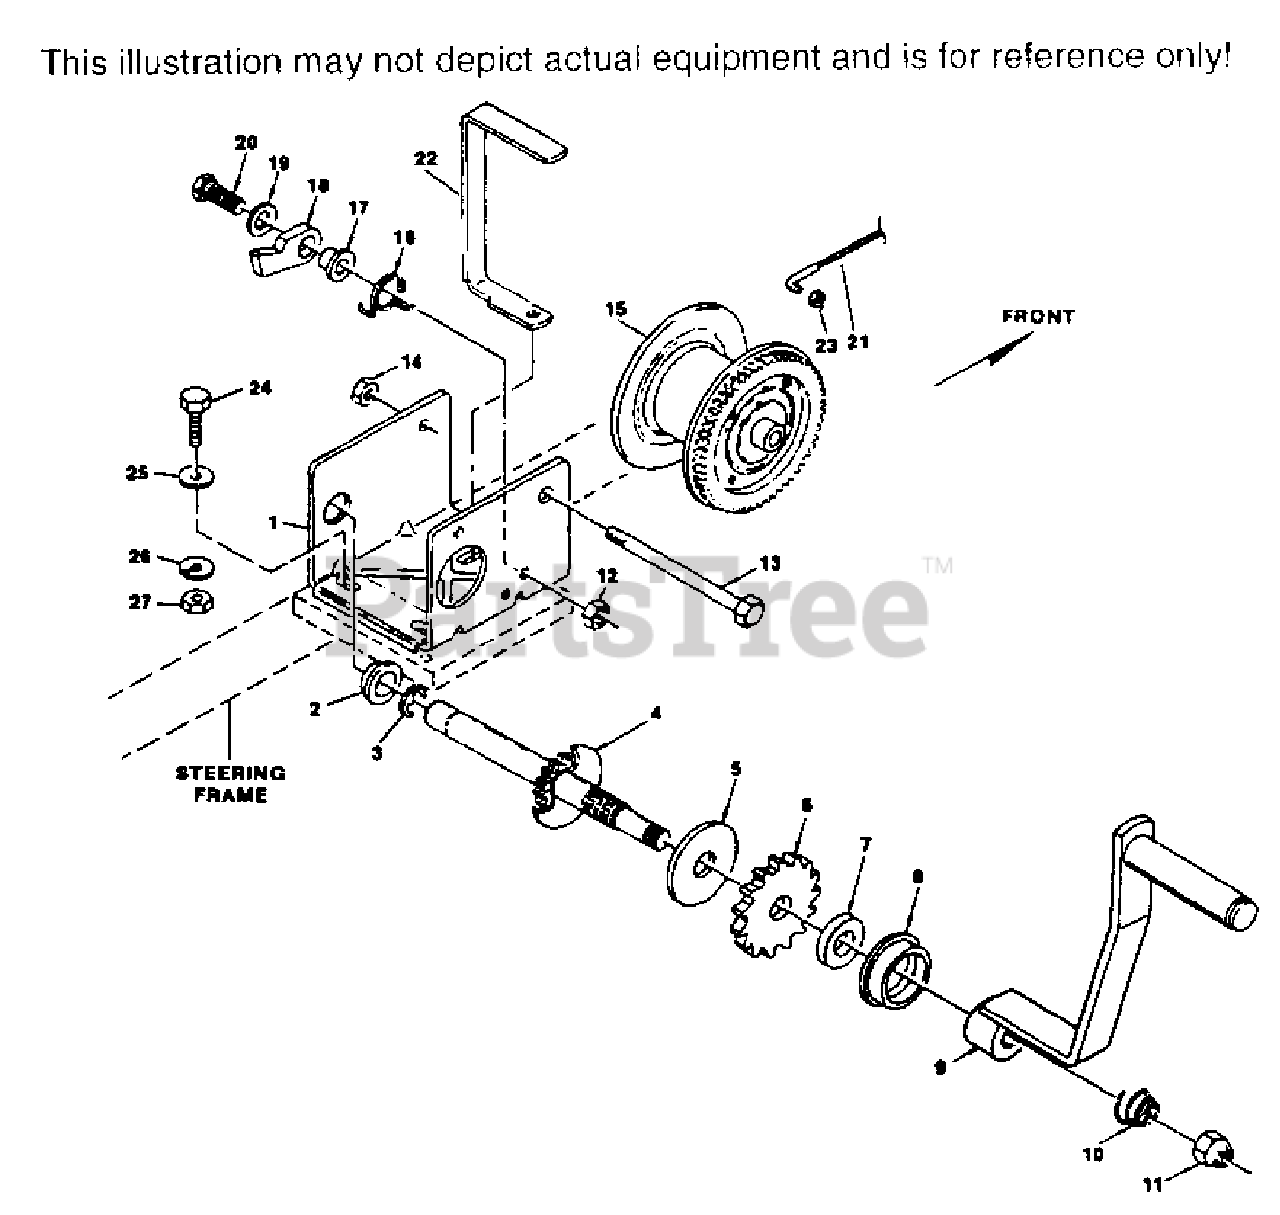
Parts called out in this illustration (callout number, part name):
1	WINCH ASSEMBLY(INCL. 1-8, 10-20)
2	SHAFT BUSHING
3	E-RING
4	DRIVE SHAFT
5	PRESSURE PLATE
6	RATCHET WHEEL
7	PRESSURE WASHER
8	SHAFT BUSHING
9	WINCH HANDLE
10	HANDLE SPRING
11	HANDLE NUT
12	HEX LOCKNUT, 3/8-16
13	REEL SHAFT
14	LOCK NUT, 7/16-14
15	WINCH REEL
17	RATCHET SPACER
18	RATCHET PAWL
19	FLAT WASHER
20	RATCHET BOLT
21	WINCH CABLE ASSEMBLY
22	CABLE GUIDE
23	HEX LOCK NUT, 1/4-28
25	FLAT WASHER, 13/32 X 13/16 X 16 GA.
26	LOCK WASHER, 3/8 SPRING
